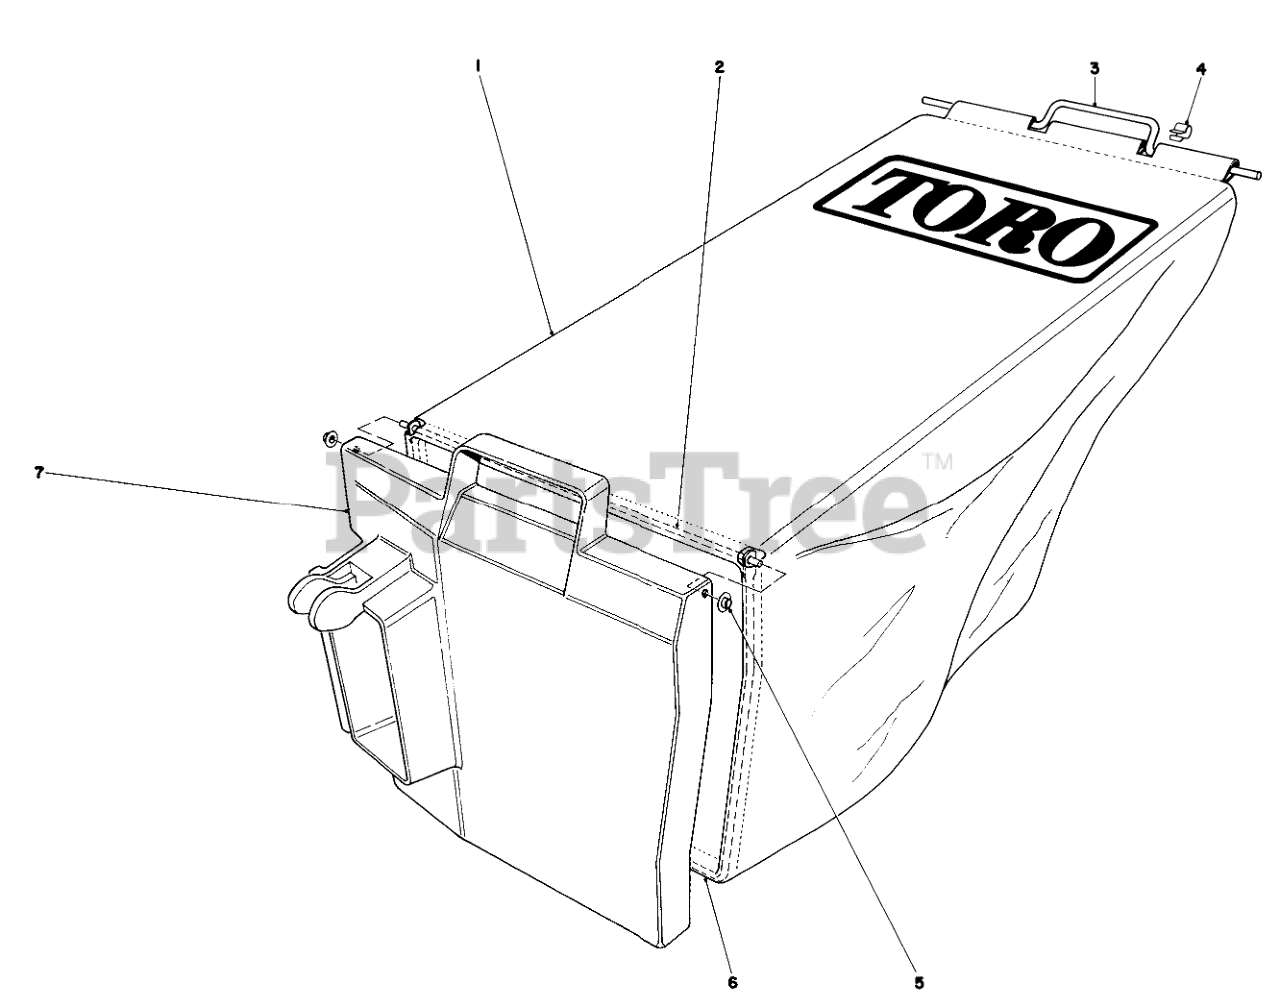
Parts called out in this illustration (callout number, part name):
1	18 BAGGER BAG 33-4552
2	HINGE
3	Handle-Bag
5	Push Nut-Washer Cap
6	Frame Bag
7	Door-Bag
